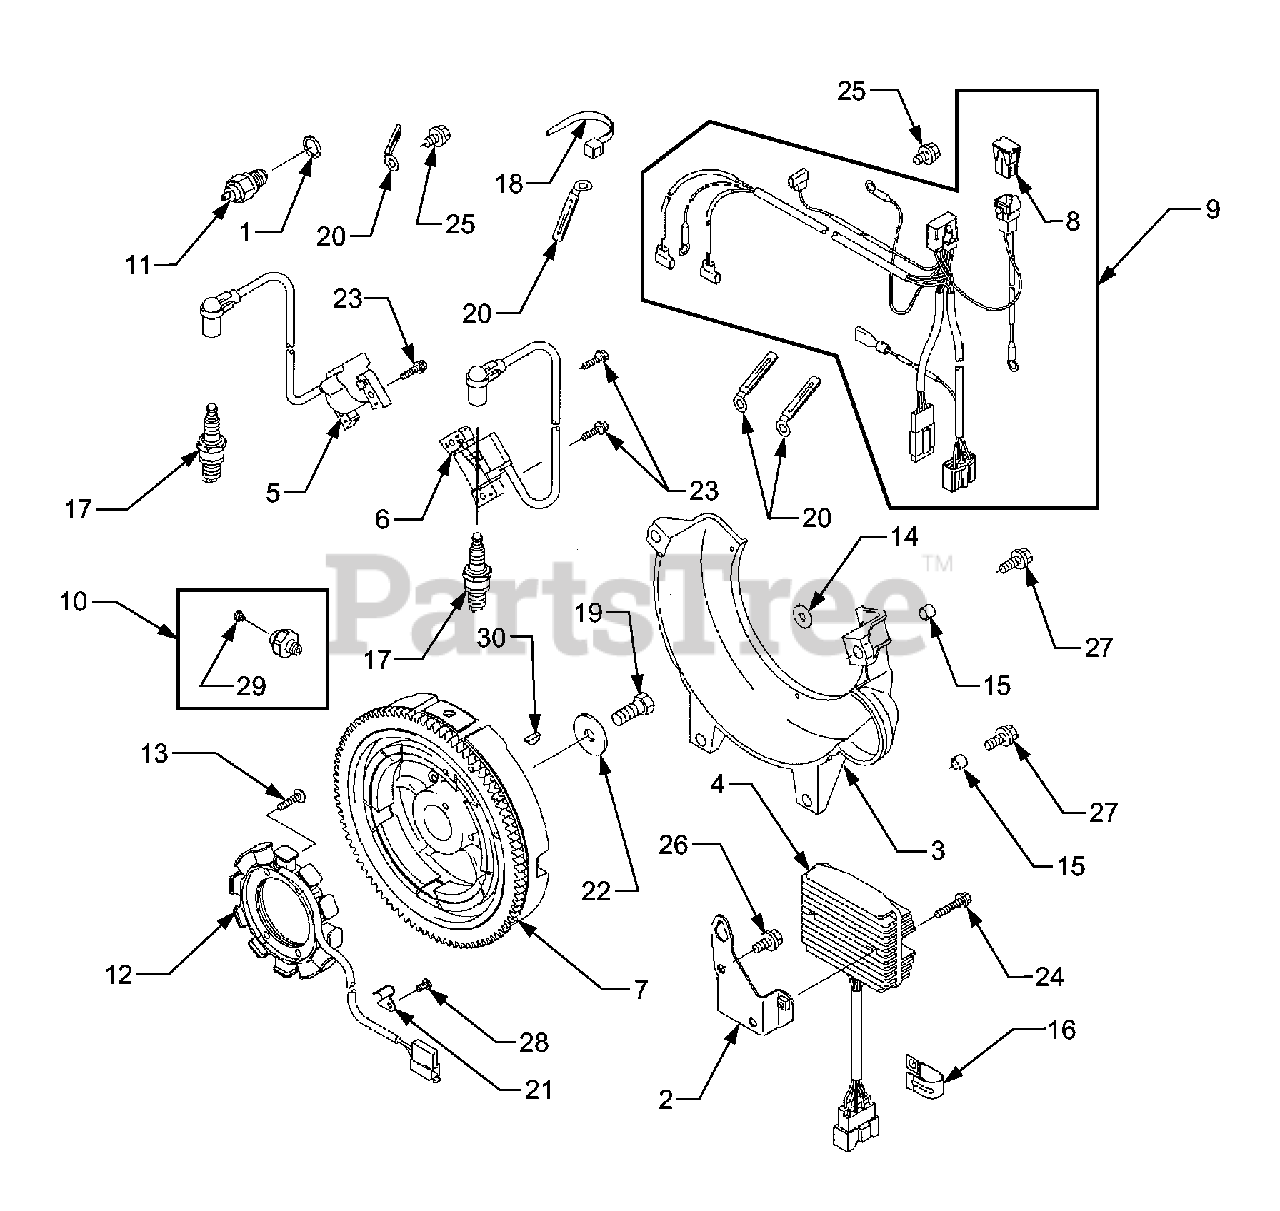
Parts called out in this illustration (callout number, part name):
3	Cover, Flywheel
4	Regulator, Voltage
5	Coil, Ignition, No. 1
6	Coil, Ignition, No. 2
7	Flywheel Assembly
9	Harness
10	Switch
12	Coil, Charging
15	Collar, 8.3 x 11.5 x 9
17	Plug, Spark
19	Bolt, 12 x 30
22	Washer, 12.2 x 40 x 3.0
23	Bolt, Flanged
24	Bolt, Flanged
25	Bolt, Flanged
26	Bolt, Flanged
27	Bolt, Flanged
30	Key, Woodruff
